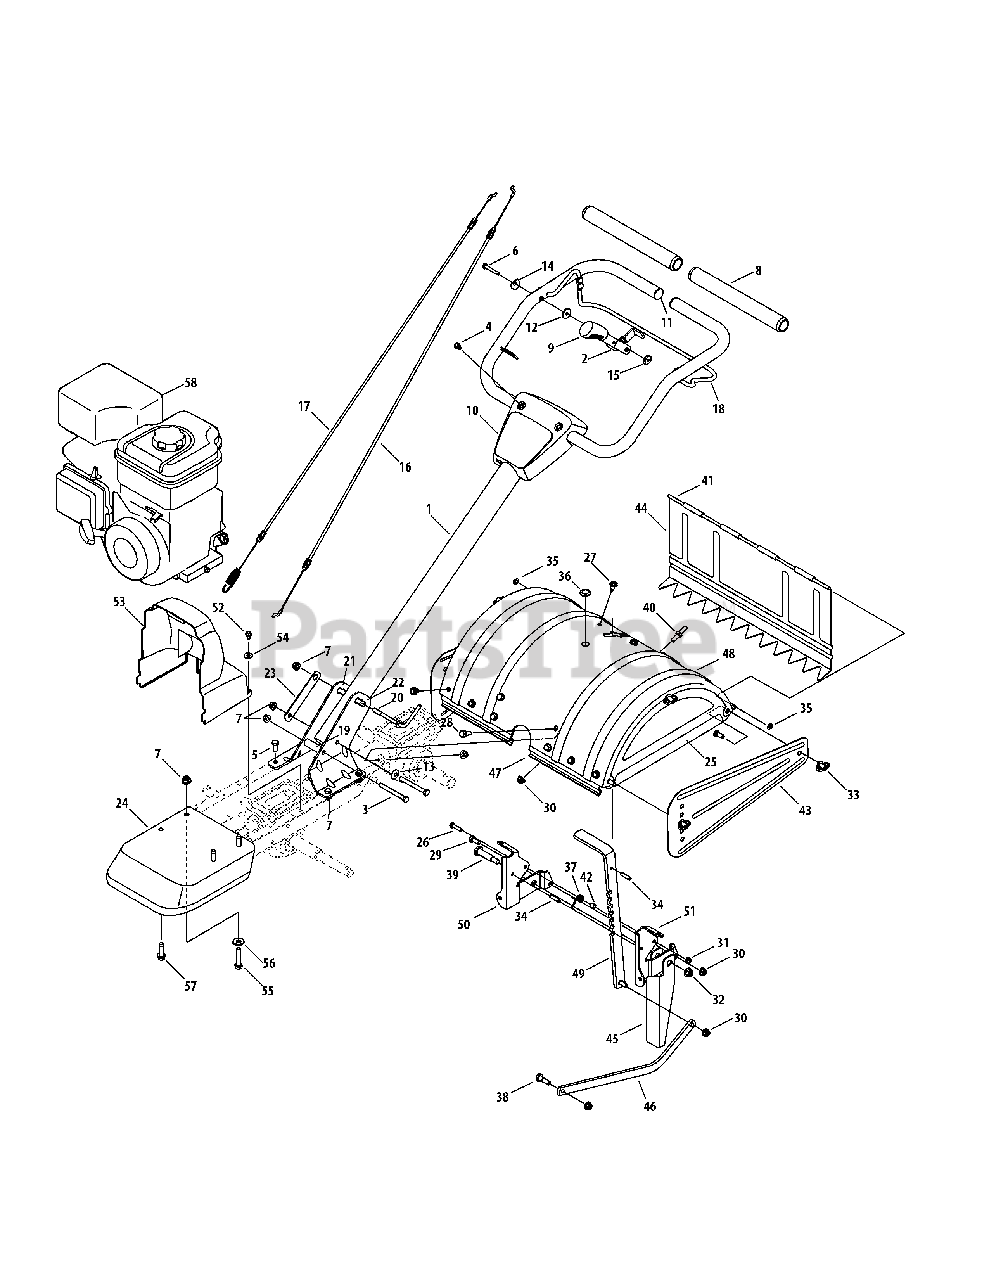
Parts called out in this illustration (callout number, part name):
1	Upper Handle Assembly
2	Reverse Handle Assembly
3	Hex Screw, 5/16-18 x 3.00
4	Hex Washer Screw, 1/4-20 x 0.500
5	Hex Washer Screw, 5/16-18 x .875
6	Hex Lock Screw, 1/4-20 x 1.62
7	Flange Lock Nut, 5/16-18
8	Foam Grip, .970 x 11.0
9	Selector Handle
10	Handle Cover
11	End Plug
12	Flat Washer, .265 x .938 x .120
13	Bell Washer, .340 x .872 x .060
14	Saddle Washer, 320 x .93 x .060
15	Shoulder Spacer, .375 x .165
16	Reverse Cable
17	Forward Cable
18	Clutch Bail
19	Spacer, .322 x .625 x 2.00
20	Handle Adjust Crank
23	Hex Flange Nut Retainer Bracket
25	End Cover Assembly
26	Hex Screw, 1/4-20 x 1.00
27	Hex Washer Screw, 5/16-18 x 0.625
28	Hex Washer Screw, 5/16-18 x .875
29	Hex Screw, 5/16-18 x .75
30	Flange Lock Nut, 5/16-18
31	Flange Lock Nut, 1/4-20
32	Flange Lock Nut, 3/8-16
33	Wing Nut w/ Bell Washer, 5/16-18
34	Spring Pin, 1/4 x 1.00
35	Cap Speed Nut, 1/4
36	Deck Hole Plug
37	Torsion Spring
38	Shoulder Screw, 5/16-18 x .405 x .435
39	Shoulder Screw, .498 x 1.635
40	Hex Screw, 5/16-18 x .75
41	Tiller Flap Rod
42	Round Spacer, .370 x .260 x .410
44	Rear Tine Shield
46	Depth Drag Bar
47	Tine Shield Mount Bracket
48	Tine Shield
49	Depth Adjustment Bracket
50	LH Tail Bracket
51	RH Tail Bracket
52	Hex Washer Screw, 1/4-20 x .500
53	Belt Cover
54	Flat Washer, .28 x .74 x .063
55	Hex Screw, 5/16-18 x 1.50
56	Bellville Washer, .827 x .331 x .098
57	Hex Screw, 3/8-16 x 1.250
58	Replacement Engine - 12T102-0751-F8
